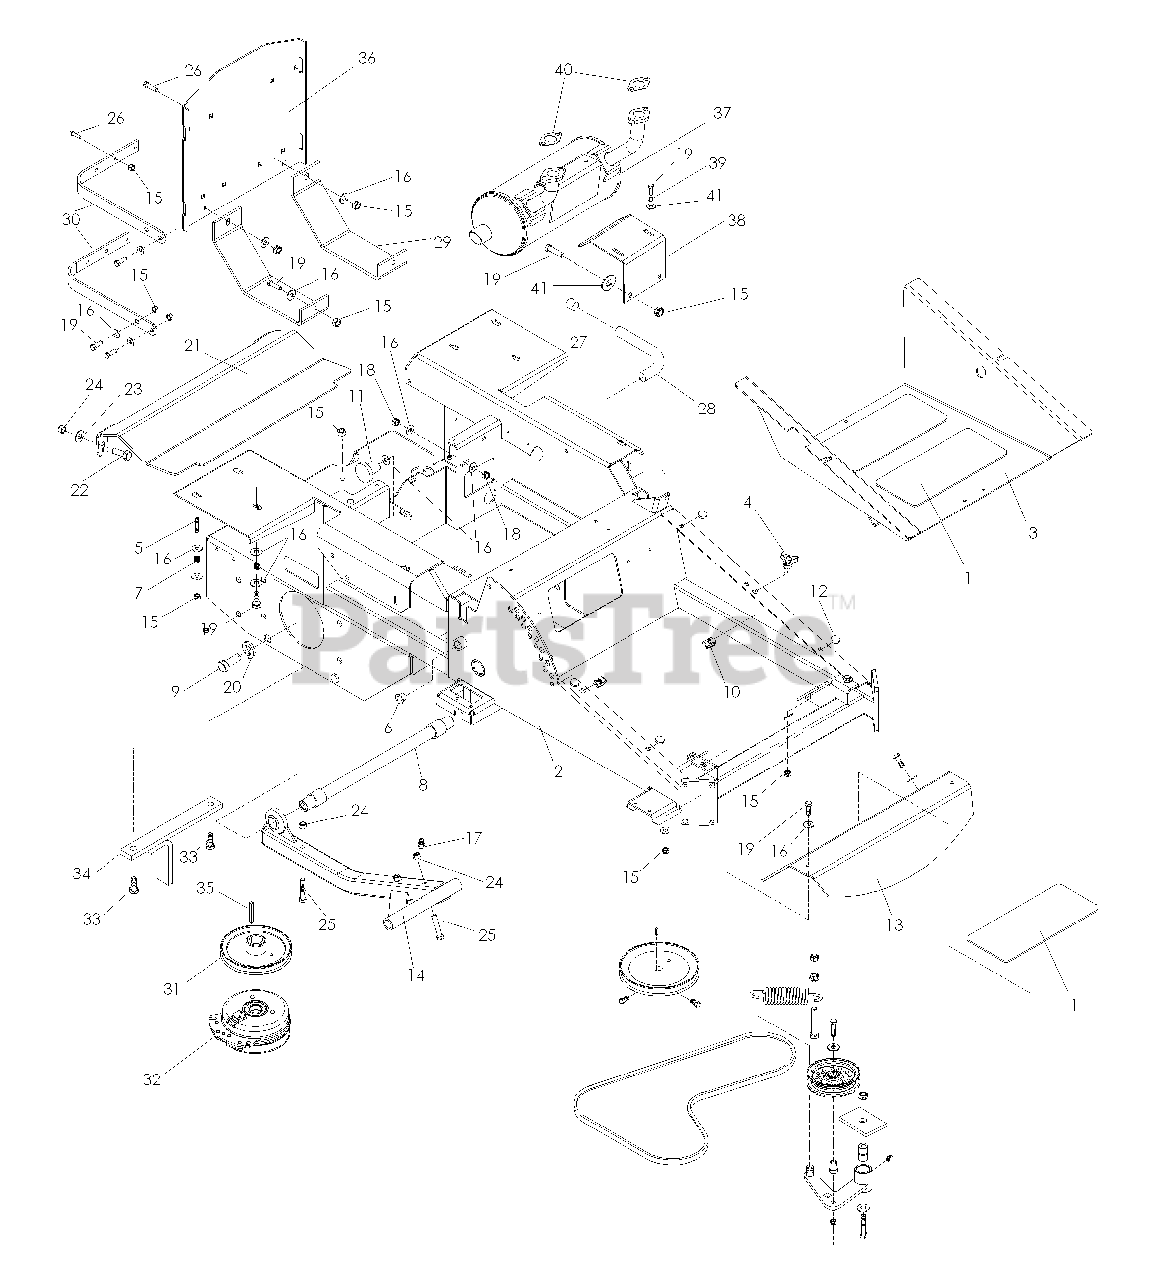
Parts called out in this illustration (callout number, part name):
1	PAD-ABRASIVE
2	FRAME W/DECALS
3	FOOT PLATE W/DECALS
4	KNOB W/STUD
5	TANK-STUD FUEL
7	SPRING, FUEL TANK
8	STRUT MOUNT
9	HCS, 5/8-11 x 2
10	NUT, 5/16-18, U-TYPE
14	STRUT, RIGHT
14	STRUT, LEFT
15	NUT 5/16-18 HEX NYLOC
16	WASHER, 5/16
17	ZERK, STRAIGHT 1/4-28
18	NUT, 5/16-18, CENTERLOCK
19	HCS, 5/16-18 x 1
20	LOCKWASHER, 5/8
21	REAR GUARD
22	HCS, 3/8 -16 X 3/4
23	WASHER, 3/8
24	NUT 3/8-16 HEX NYLOC
25	HCS, 3/8 -16 x 2
26	RHSNB, 5/16 -18 x 1
28	HOSE-DRAIN
29	SKID PLATE
32	CLUTCH MODEL 968999771
32	CLUTCH MODEL 96899974
33	HCS, 5/16 -18 x 1 3/4
34	CLUTCH TIE DOWN
35	KEY, 1/4 SQ x 1 1/4
36	ENGINE GUARD
37	MUFFLER MODEL 96899974
38	BRACKET MUFFLER MODEL 96899974
39	LOCKWASHER 5/16
41	WASHER, 5/16
